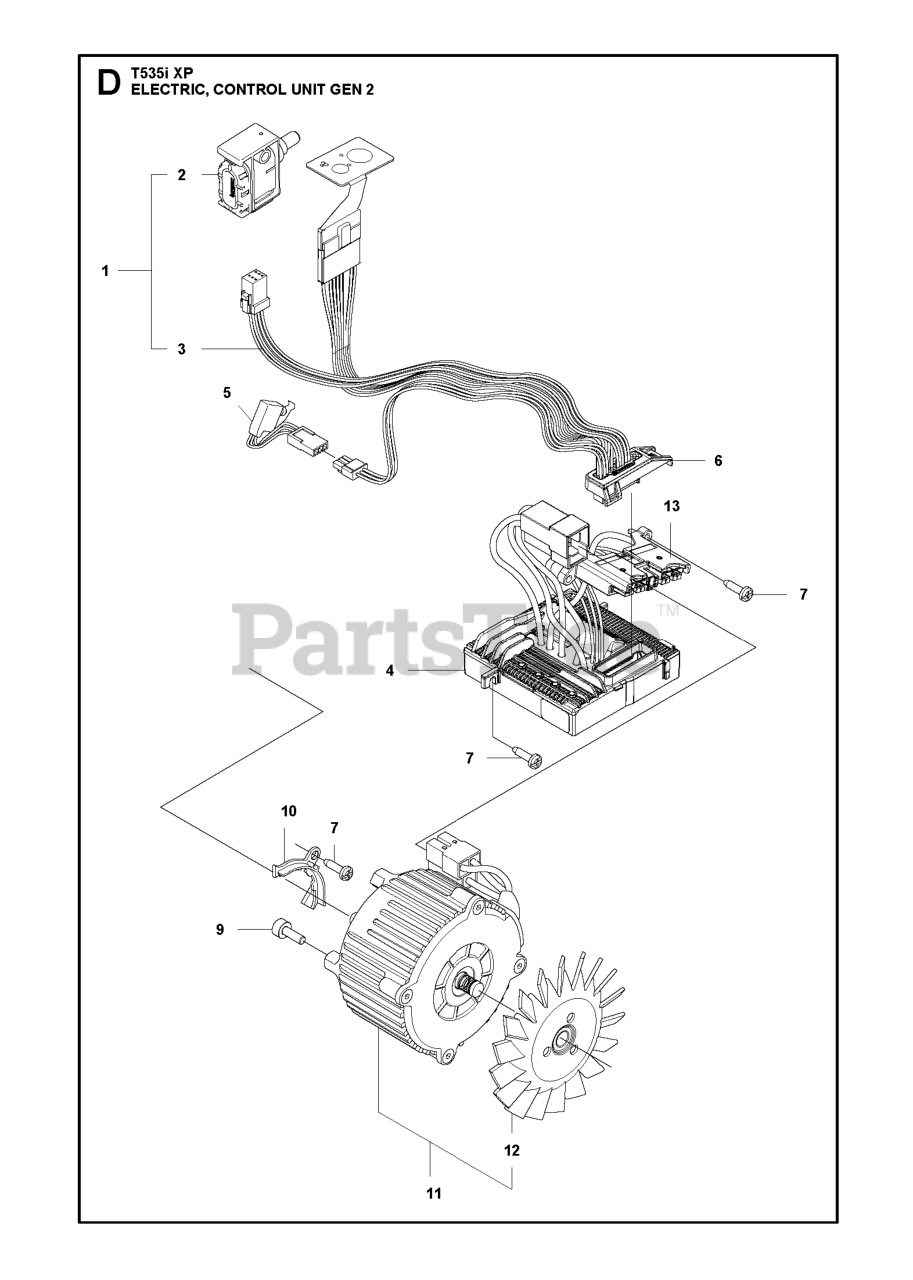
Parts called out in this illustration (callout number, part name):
1	SWITCH KIT BATTERY TOP HANDLE
2	TRIGGER SWITCH IPX4
3	WIRING ASSY SIGNAL TOPHANDLE
4	CONTROL UNIT
5	WIRING ASSY
11	MOTOR ASSY BLDC D70
13	CONNECTOR BATTERY
